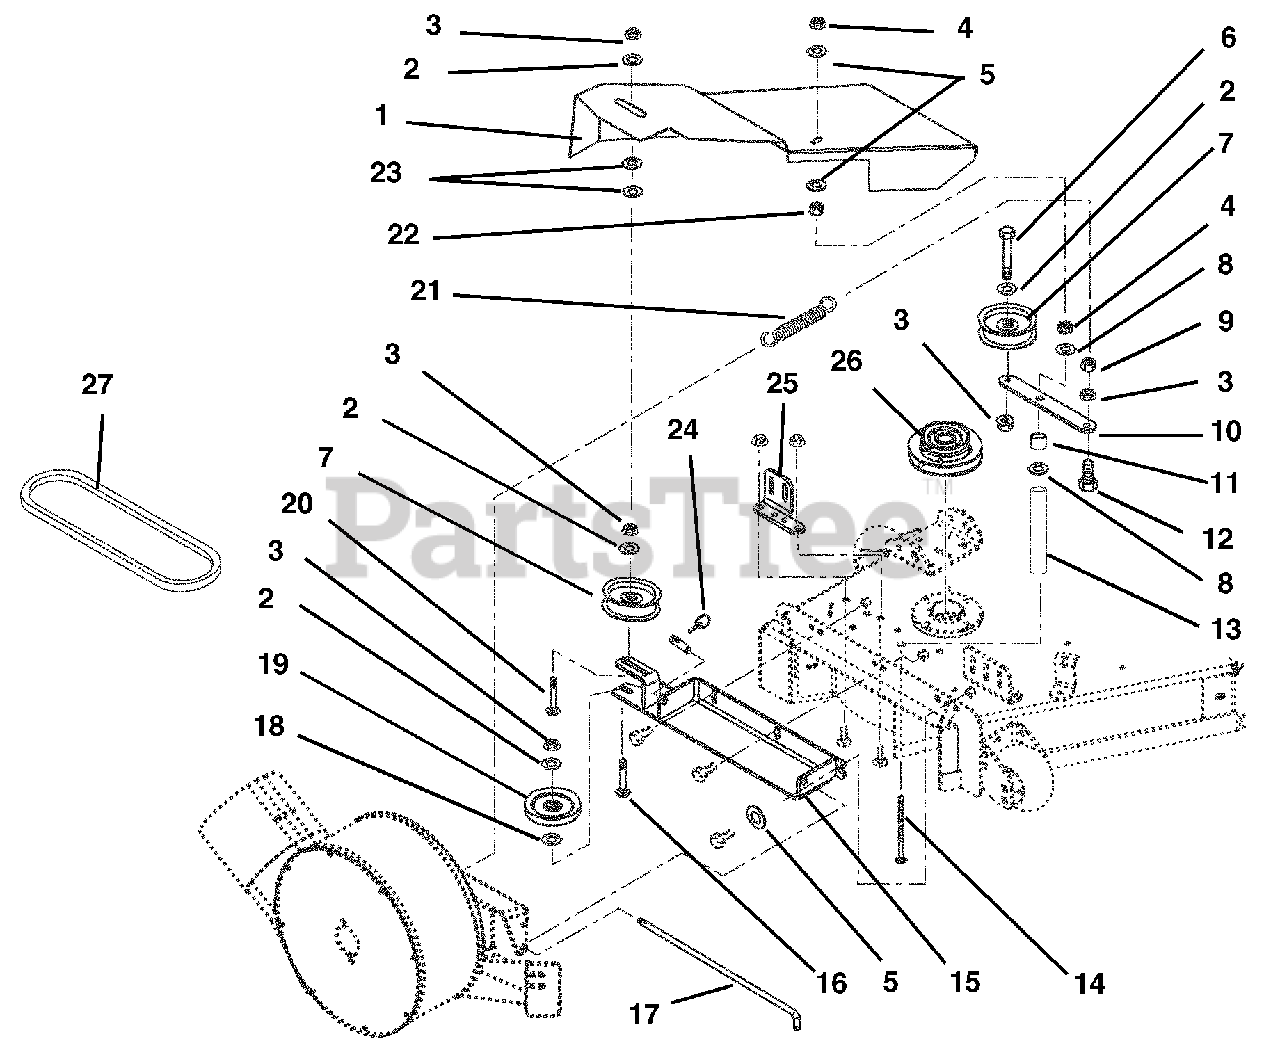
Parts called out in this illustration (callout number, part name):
1	GUARD, BAGGER
2	@WSHR-FL-STL.438X1.00X.083 YWZ
3	@NUT-LK-TOP-FLG .38-16 YWZC
4	@NUT-LK-TOP-FLG .31-18 YWZC
5	@WSHR-FL-STL.38X.875X.083 YWZC
6	@BLT-HEX .38-16X1.75 GR5 YWZC
7	IDLER FLANGED 3.50
8	WSHR-FL-STL .344X1.125X.135
9	@NUT-LK-CTR .38-16 YWZC
10	ARM, IDLER
11	SPACER .380X.503X.281
12	@BLT-HEX .38-16X1.25 GR5 YWZC
13	SPACER .391 ID X .62 OD X 1.0
14	BLT-RDHDSQNKFT.312-18X4.0 G5YZ
15	WMT, PIVOT MOUNT 44,48,52
16	@BLT-RDHDSQNK .38-16X1.75 G5YZ
17	ROD-PIVOT
18	WSHR-FL-STL .406X1.00X.188 YWZ
19	IDLER-V 4.00 X .38 NWHAMSHR
20	@BLT-RDHDSQNK .38-16X2.50 G5YZ
21	SG-TENS .080X.687X5.16 WLD 28
22	@NUT-LK-CTR .31-18 YWZC
23	WSHR-FL-STL .406X1.375X.135 YZ
24	PIN-KLIK 1.000X.188X1.25 YWZC
25	BRKT, DECK MTG. 44, 48
25	44" & 48" DECK MTG BRKT - RED
25	BRKT, 52" DECK MTG.
25	52" DECK MTG BRACKET - RED
26	PULLEY, DOUBLE V 3.50/5.25 DIA
27	V-BELT, A-RAW EDGE
27	V-BELT, 4L-RAW EDGE
